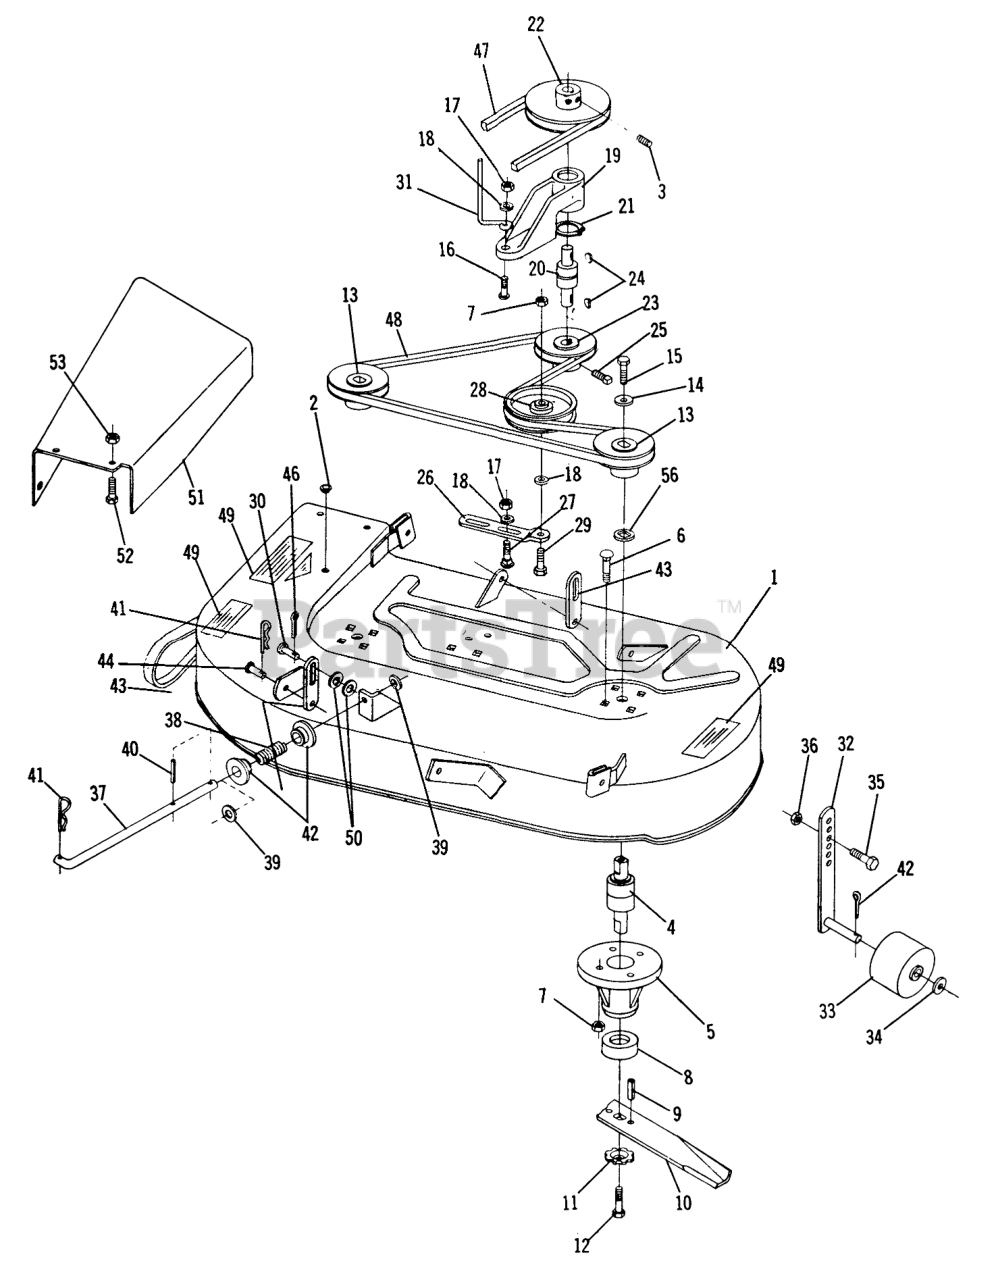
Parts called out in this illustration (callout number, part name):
2	Plug Button
3	Set Screw
4	BEARING
5	Housing
6	Bolt Carriage 3/8-16 x 1
8	CUP-SPINDLE
9	SPIROL ROLL PIN
10	BLADE KIT (2-100328)
11	WASHER
12	Bolt 3/8-16 x 7/8
13	PULLEY
14	WASHER
15	Bolt 3/8-16 x 3/4 Hex
16	Bolt 3/8-16 x 1
17	3/8-16 E.S.
18	Washer
19	Jack Shaft Housing
20	INTEGRAL BEARING SHA
21	Snap Ring
22	Pulley-Drive-Upper
22	PULLEY-UPPER DRIVE
23	Pulley-Drive-Lower
23	PULLEY-LOWER DRIVE
24	KEY-WOODRUFF
25	Set Screw-5/16-18 x 3/8
26	Bracket
27	Bolt 3/8-16 x 1
28	Idler Pulley
29	Bolt Hex 3/8-16
31	Guide Belt
32	Roller Arm
33	ROLLER ASSY
34	Washer
35	Bolt 5/16-18 x 1
36	Nut 5/16-18
37	Rod-Link
38	SPRING
39	Washer
40	PIN-ROLL
41	Hairpin
42	BUSHING
43	Link-Lift
44	Clevis Pin 3/8 x 3/4
45	Link-Lift-Fram
46	Hairpin
47	V BELT
48	Belt-55" Mower
49	Decal
50	Washer
51	Extension-Chute
52	Bolt 5/16-18 x 5/8
53	Nut-Nylok
54	DecaI-Warning
55	Decal
56	WASHER
